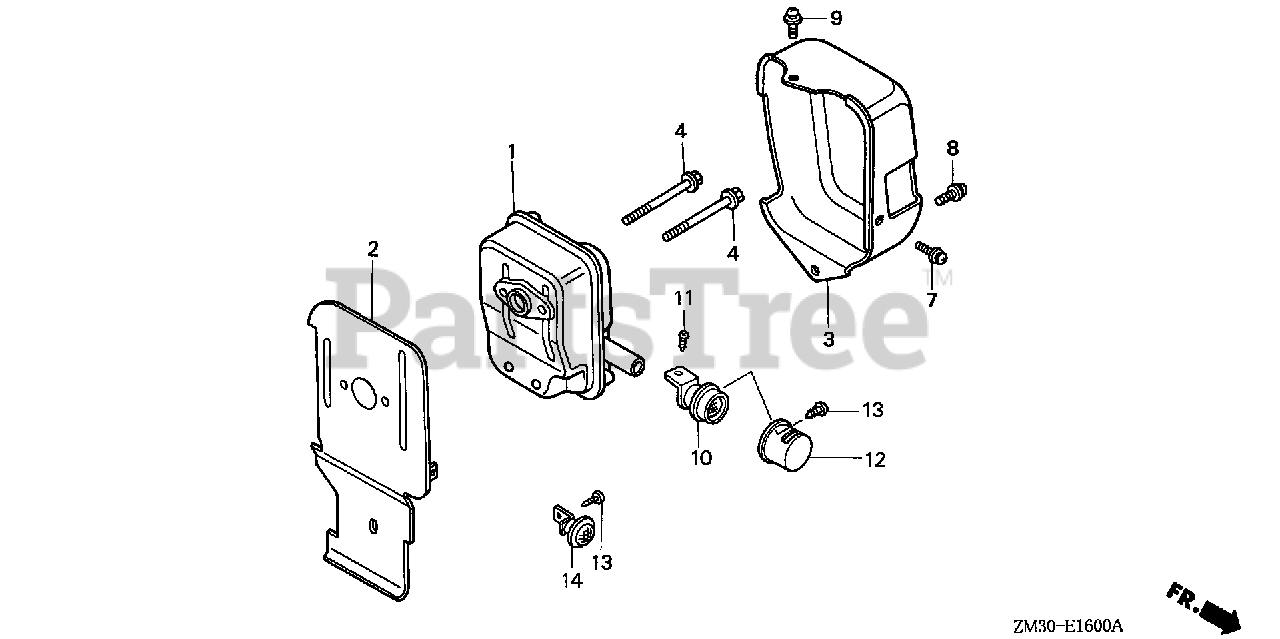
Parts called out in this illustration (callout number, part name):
2	GUIDE, AIR EX.
3	INNER COVER, TOP
4	BOLT, FLANGE (5X50)
7	SCREW-WASHER (5X8)
8	SCREW-WASHER (5X10)
9	SCREW-WASHER (5X16)
13	SCREW, TAPPING (4X6)
14	ARRESTER, SPARK
